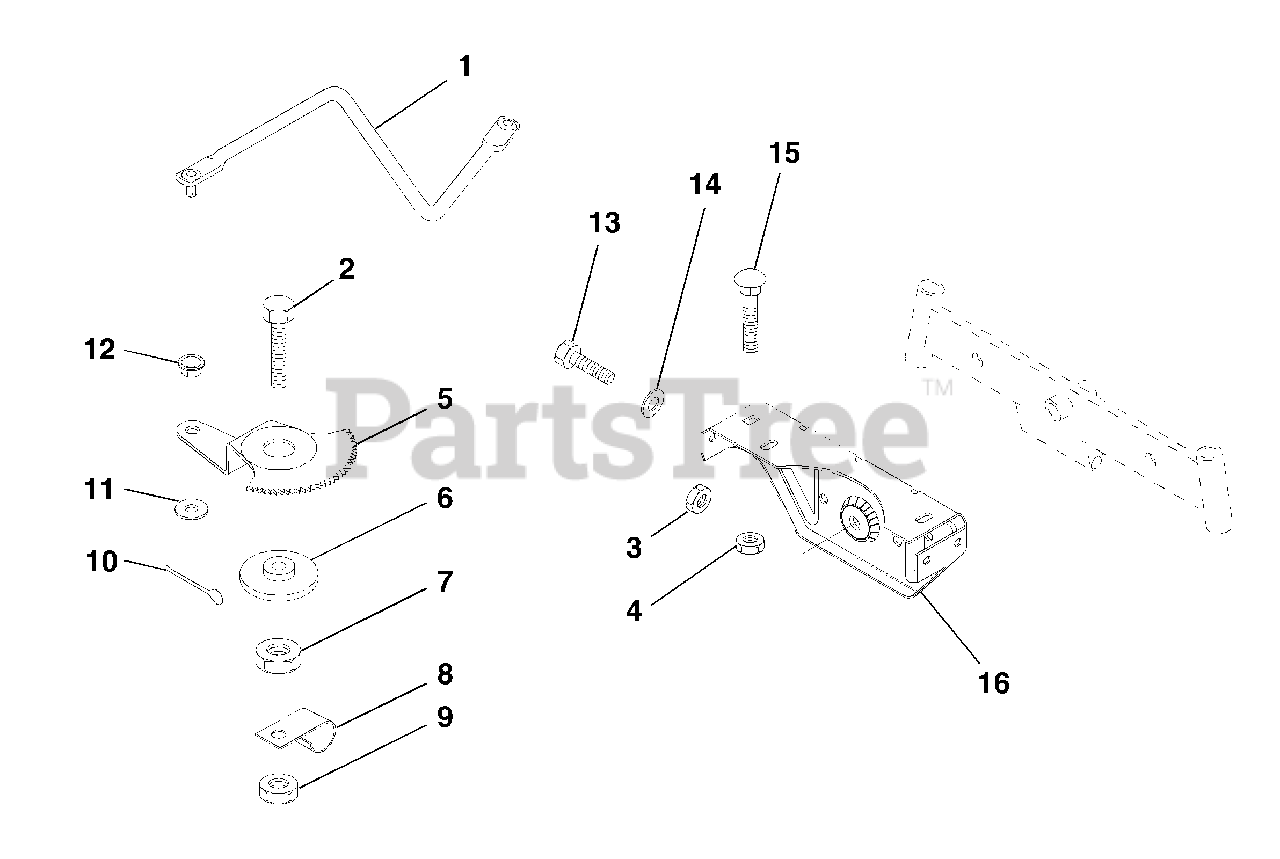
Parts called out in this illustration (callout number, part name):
1	Link, Drag
2	Bolt, Fin Hex 1/2-13 x 1-3/4
3	Nut, Lock Hex w/Ins. 5/16-18
4	Nut, Lock Hex w/Wsh 3/8-16
5	Gear, Sector
7	Nut, Heavy Hex Top Lock 1/2-13 UNC
8	Clip, Insulated
9	Nut, Crownlock 3/8-16
10	Pin, Cotter 1/8 x 3/4
11	Washer, 13/32 x 13/16 x 16 Ga.
13	Bolt, Hex Hd. 5/16-18 UNC x 3/4
14	Washer 11/32 x 7/8 x 16 Ga.
15	Bolt, Carriage 3/8-16 UNC x 3/4
16	Support, Front Axle
